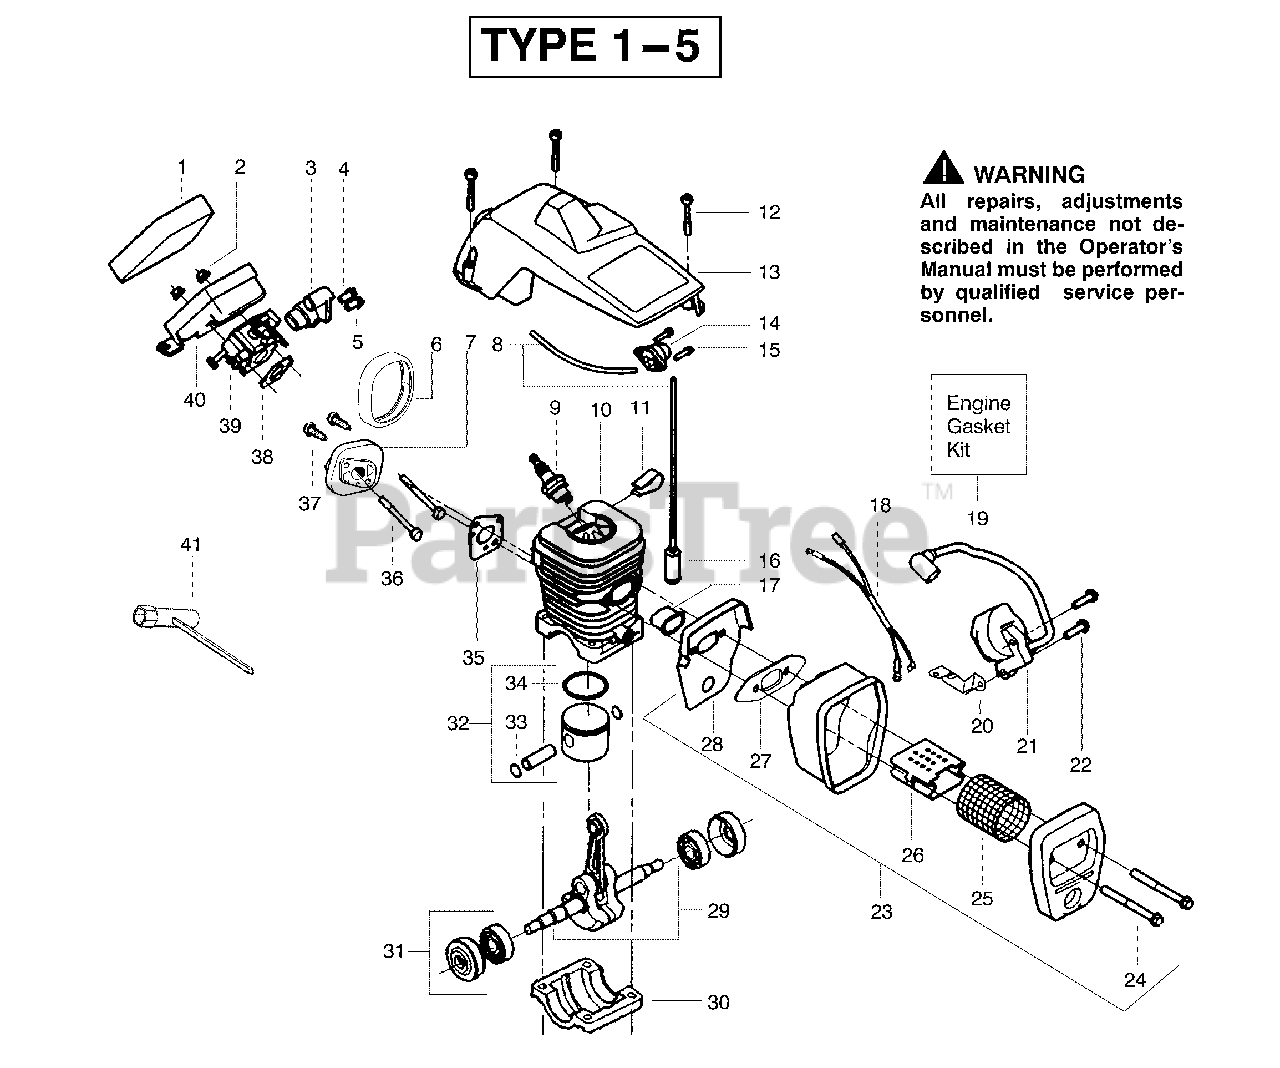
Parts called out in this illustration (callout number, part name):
1	Foam- Air Filter
3	Grommet-Carb Adjust
4	Limiter Cap-High
5	Limiter Cap-Low
6	Seal-Carb Adapter
7	Carb. Adapter
8	Fuel Line Kit (Small)
9	Spark Plug (RCJ-7Y)
10	Cylinder Kit
11	Clip-High Tension Lead
13	Cylinder Shield
14	Air Purge Ass'y.
16	Fuel Pick-up Ass'y.
17	Heat Insulator
18	Assy. -Wire Harness
19	Kit-Engine Gasket
20	Strap-Ground
21	Module- Ignition
23	Assy-Muffler
25	Screen-Spark
26	Diffuser-Muffler
27	Gasket-Muffler (Kit)
28	Backplate-Muffler
29	Assy. - Crankshaft
30	Cap-Crankcase
31	Assy.-Seal & Bearing
32	Kit-Piston
33	Retainer-Piston Pin
34	Ring - Piston
35	Gasket-Carb. Adap. (Kit)
38	Gasket - Carb. (Kit)
39	Kit-Carburetor
40	Housing- Air Filter
41	Wrench - Bar
